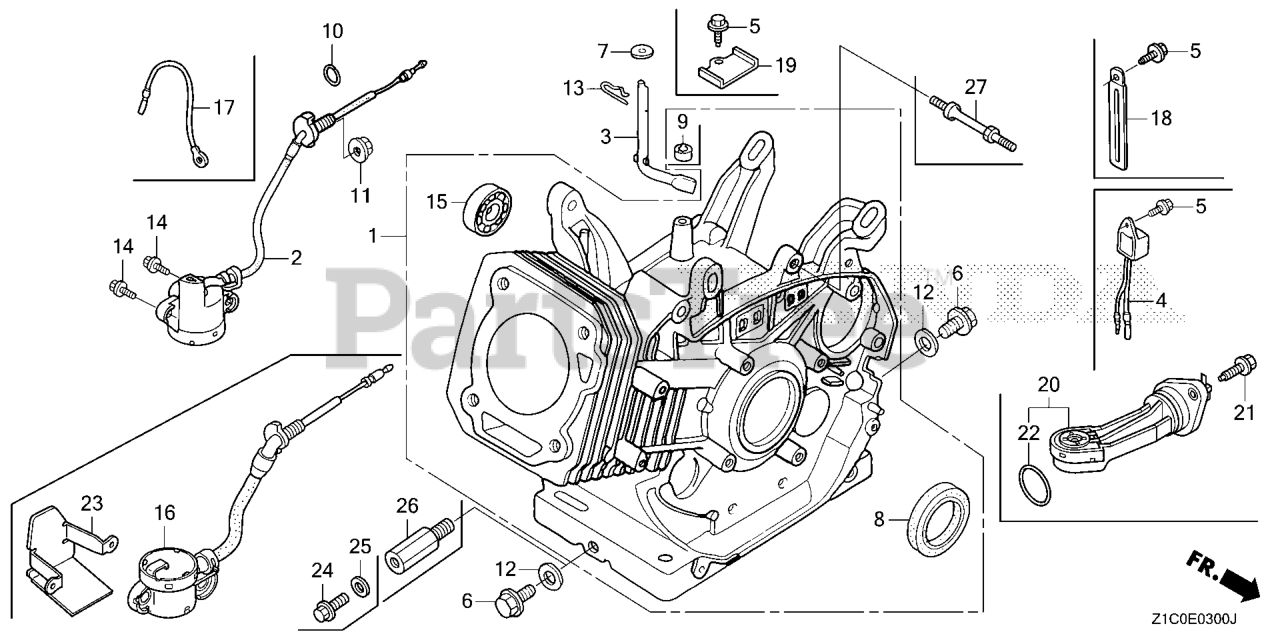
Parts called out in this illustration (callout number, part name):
1	CYLINDER ASSY.
3	SHAFT, GOVERNOR ARM
6	BOLT, DRAIN PLUG
7	WASHER (8.2X17X0.8)
8	OIL SEAL (35X52X8) (NOK)
8	OIL SEAL (35X52X8)
9	OIL SEAL (8X14X5)
12	WASHER, DRAIN PLUG (12MM)
13	PIN, LOCK (10MM)
15	BEARING, RADIAL BALL (6202)
15	BEARING, RADIAL BALL (6202) (FUJIKOSHI)
